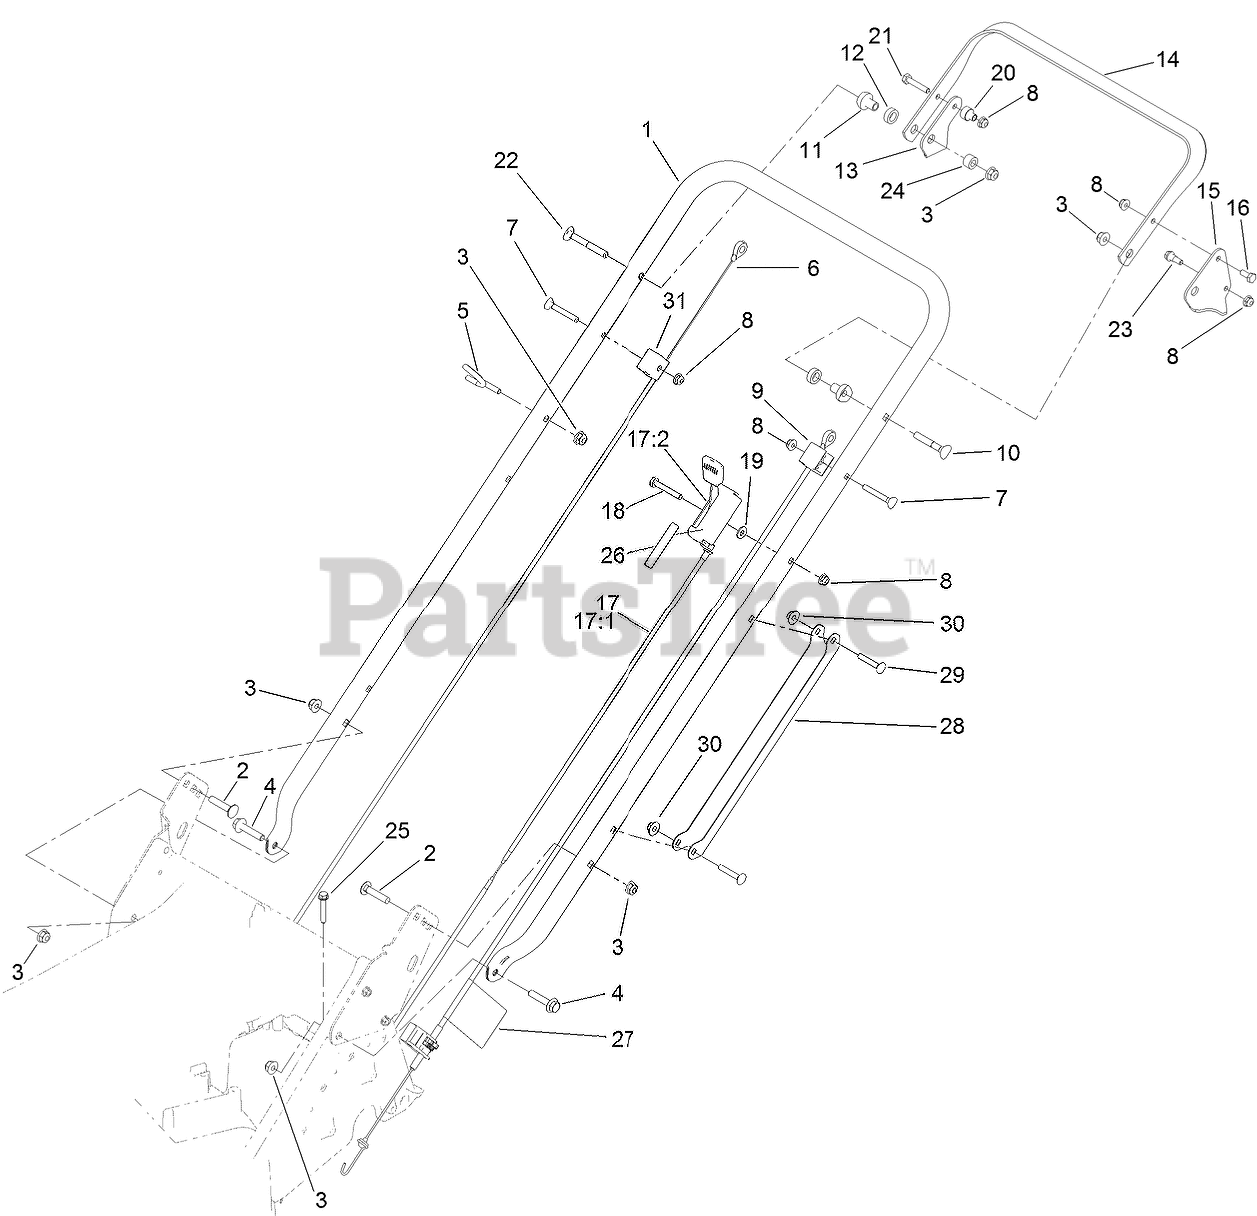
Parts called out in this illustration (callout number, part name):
1	HANDLE
2	BOLT-CARR
3	NUT-HF, NI
4	SCREW-HHF
5	GUIDE,ROPE
6	CABLE-BRAKE
7	SCREW-HANDLE
8	NUT-HF
9	CABLE-TRACTION
10	SCREW-HANDLE
11	SPACER-SUPPORT
12	SPACER-NYLON
13	LEVER-CONTROL, BRAKE
14	BAR-CONTROL, ZONE START
15	LEVER-CONTROL, TRACTION
16	SCREW-HH
17	CONTROL-THROTTLE/CHOKE
17:1	CABLE-THROTTLE
17:2	CONTROL-THROTTLE
18	SCREW-HH
19	WASHER-FLAT
20	SPACER-STEPPED
21	SCREW-HH
22	SCREW-HANDLE
23	BOLT-SHOULDER
24	SPACER
25	SCREW-HWH
26	DECAL-THROTTLE, CHOKE
27	DECAL-ADJUST, SELF PROPEL DRIVE
28	GUARD-CABLE, HANDLE
29	SCREW-CARR
30	NUT-HEX FLG
31	ANCHOR-CABLE
